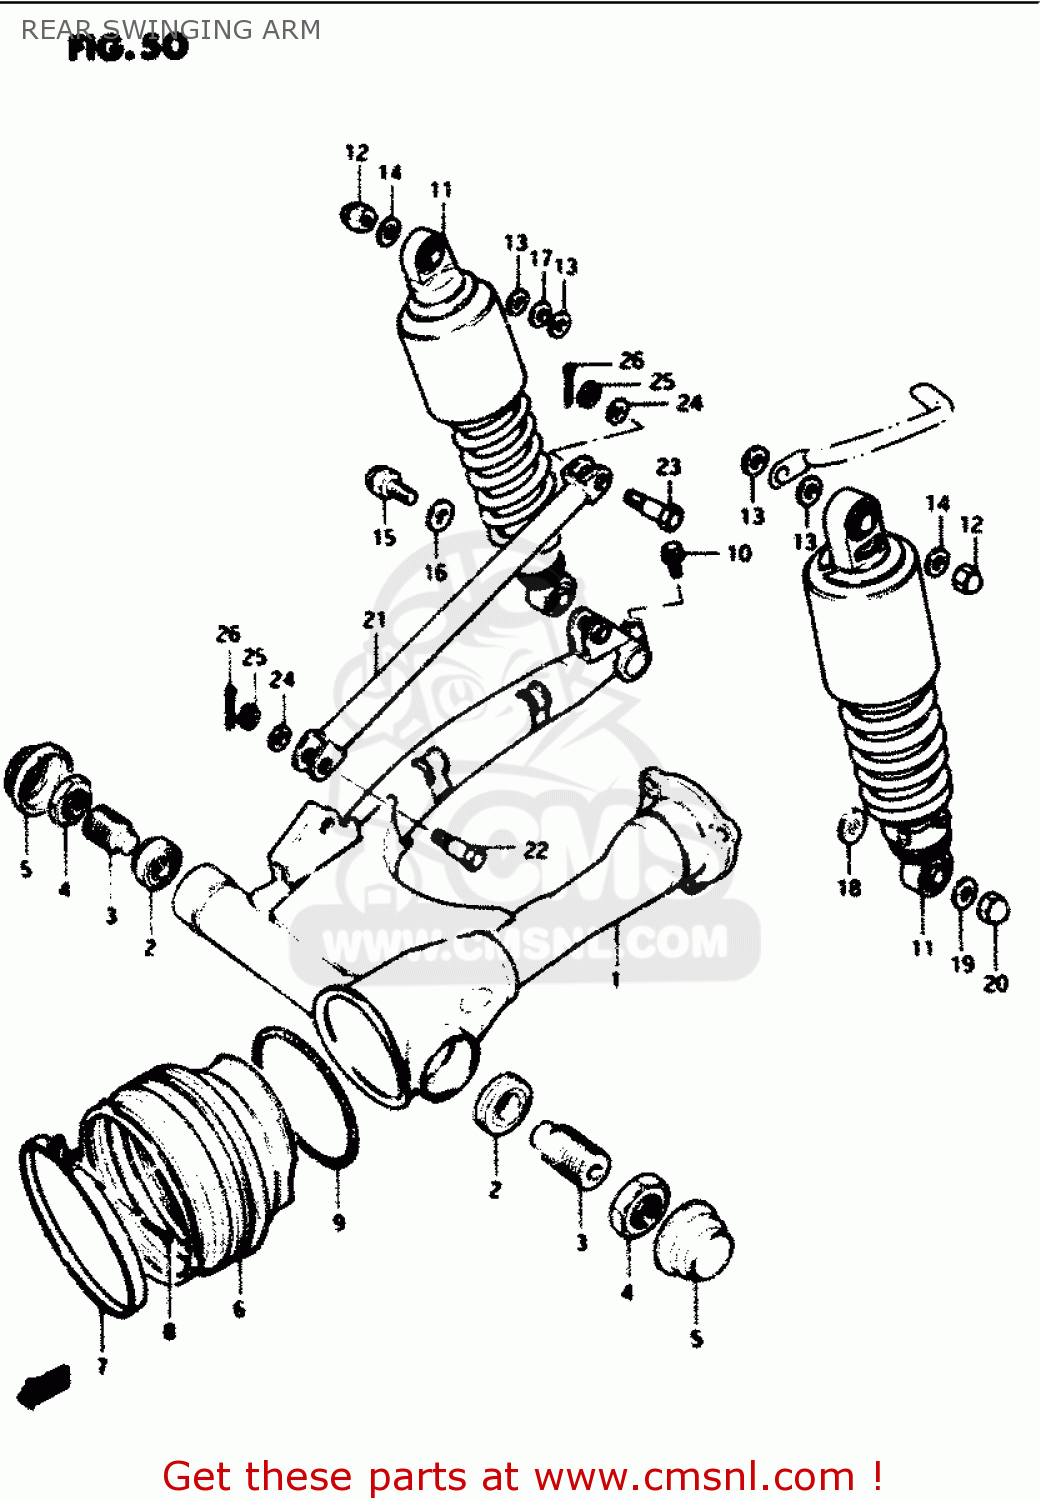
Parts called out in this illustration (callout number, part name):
1	SWING ARM SET,REAR (B
2	BEARING(17X40X13.25)
3	BOLT,REAR SWING ARM PIVOT
4	NUT
5	CAP,REAR SWING ARM PIVOT
6	BOOT,PROPELLER SHAFT
7	CLAMP
8	SCREW 4X25
9	SPRING,PROPELLER SHAFT
10	BOLT
11	ABSORBER ASSY,RR SHOCK
12	NUT
13	WASHER
14	WASHER
15	BOLT 12X33
16	WASHER (12.5X24X1.6)
17	WASHER (12.5X24X3.2)
18	WASHER
19	WASHER
20	NUT, LOWER LH
21	TORQUE LINK,REAR
22	BOLT
23	BOLT(10X39)
24	WASHER 10MM
25	NUT
26	PIN 20X20
